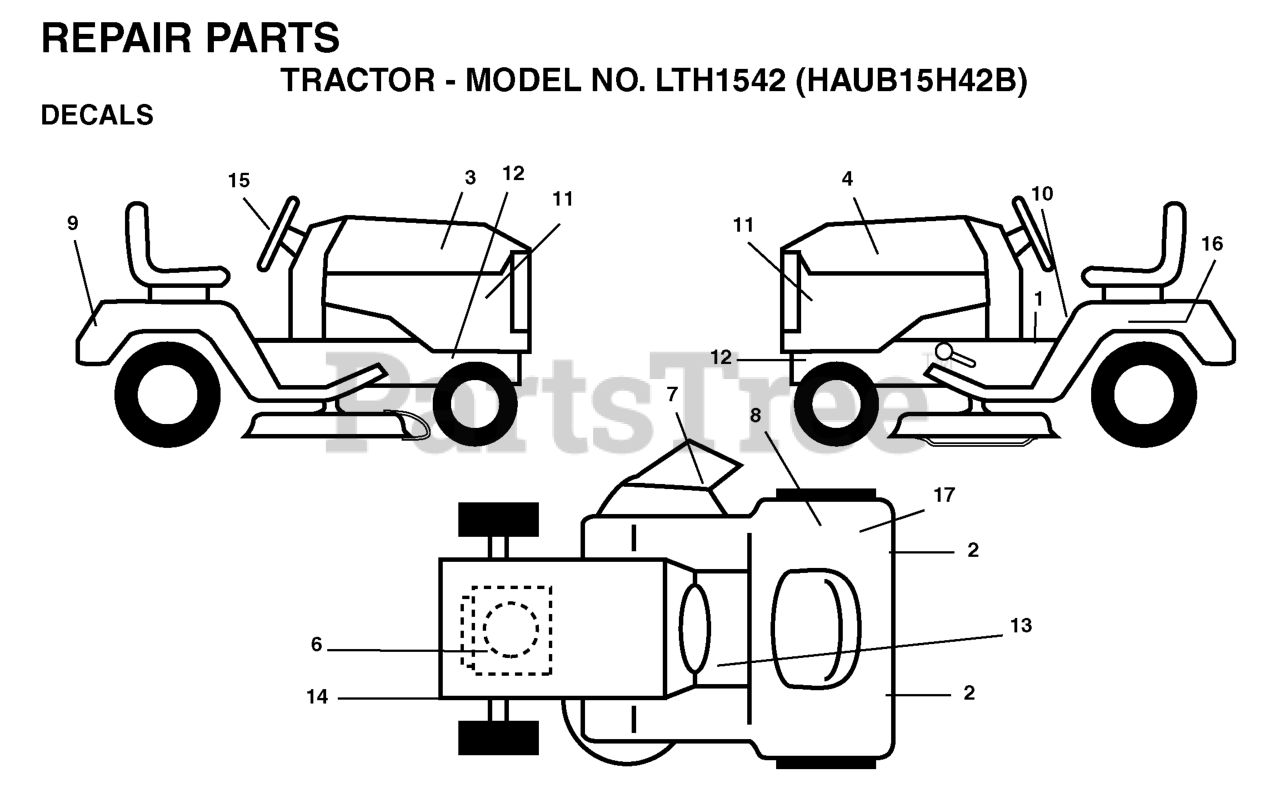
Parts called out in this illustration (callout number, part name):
1	DECAL READ OWNER'S MAN SYMS
2	REFLECTOR-TAIL YT
7	DECAL DECK "B" 42"
8	DECAL
9	DECAL, FENDER
10	DECAL PARK BRAKE
11	DECAL PNL SIDE
13	DECAL
14	DECAL V BELT SCHEMATIC
15	DECAL.WHEEL.STEERING.HUSQ.PERM
16	DECAL BTRY SYMBOLS
17	DECAL.INTERNATIONL.CUTFINGER
